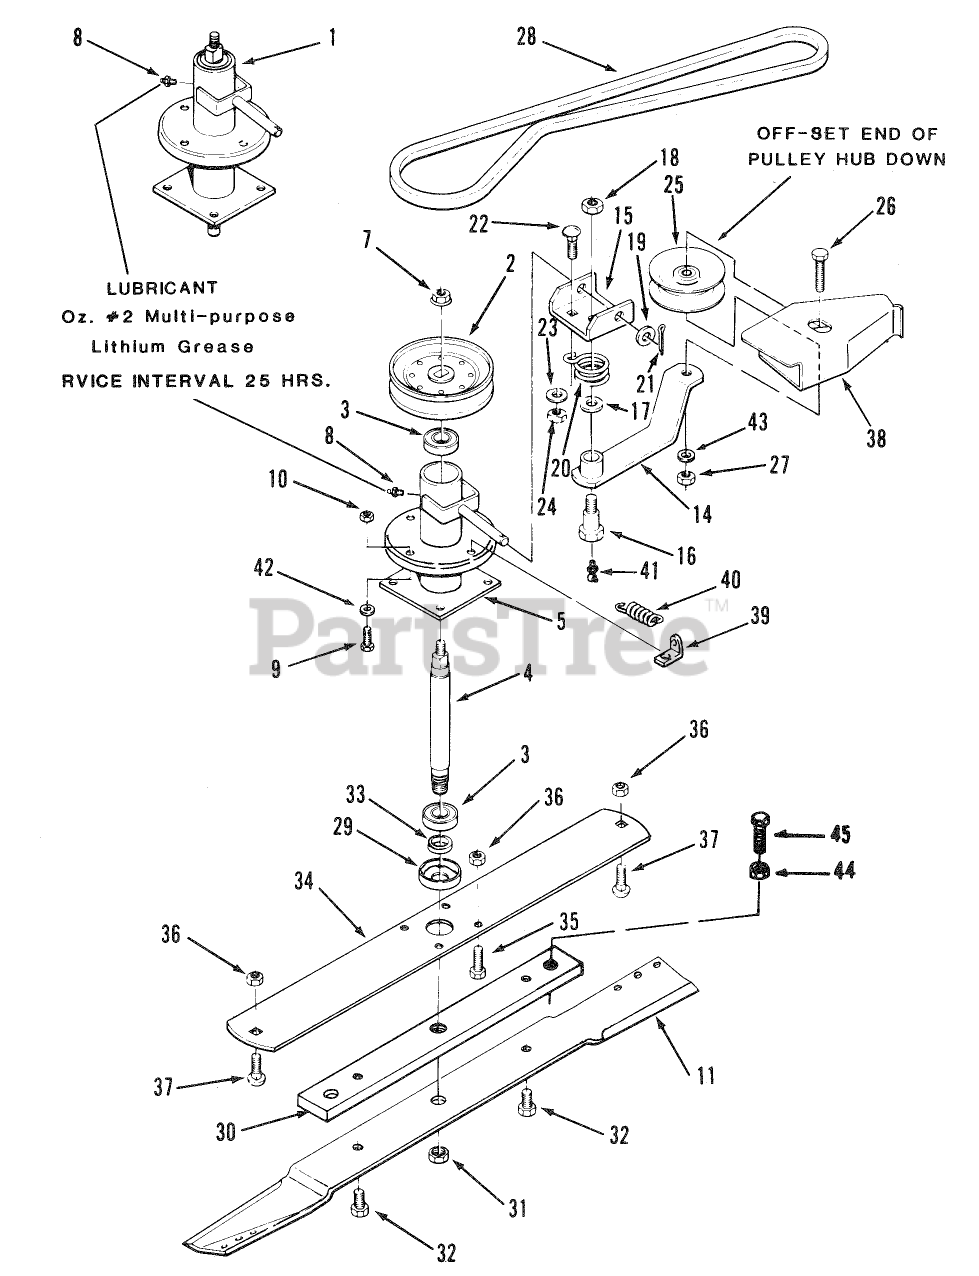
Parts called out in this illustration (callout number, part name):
1	Spindle Complete (includes items 3, 4, 5 & 8)
2	PULLEY SPINDLE
3	BALL BEARING
4	SHAFT SPINDLE
5	ASS'Y-BLADE HOUSI R
7	NUT 3/8-24 WHIZLOCK
8	Zerk
9	Bolt
10	Nut
11	Blade
14	ASSY LEVER R
15	CHANNEL PIVOT R
16	SHOULDER BOLT
17	WASHER
18	NUT-JAM(7/16-14)
19	Washer
20	SPRING-TORSION
21	Cotter Pin
22	Bolt
23	Washer
24	NUT
25	PULLEY IDLER R
26	Bolt
27	NUT
28	BELT-V, LOWER PTO
29	CUP SPINDLE
30	BAR-BLADE R
31	X-REF 3220-6
32	HEX BOLT 1/2-13X3/4
33	SPACER-BLADE
34	PLATE SUPPORT R
35	BOLT
36	NUT
37	Carriage Bolt 3/8-16 X 3/4
38	COVER BELT R
39	CLIP - SPRING
40	SPRING-EXTENSION
41	ZERK 90DEGREE
42	Lockwasher
43	WASHER
44	NUT-HEX, JAM
45	Bolt
